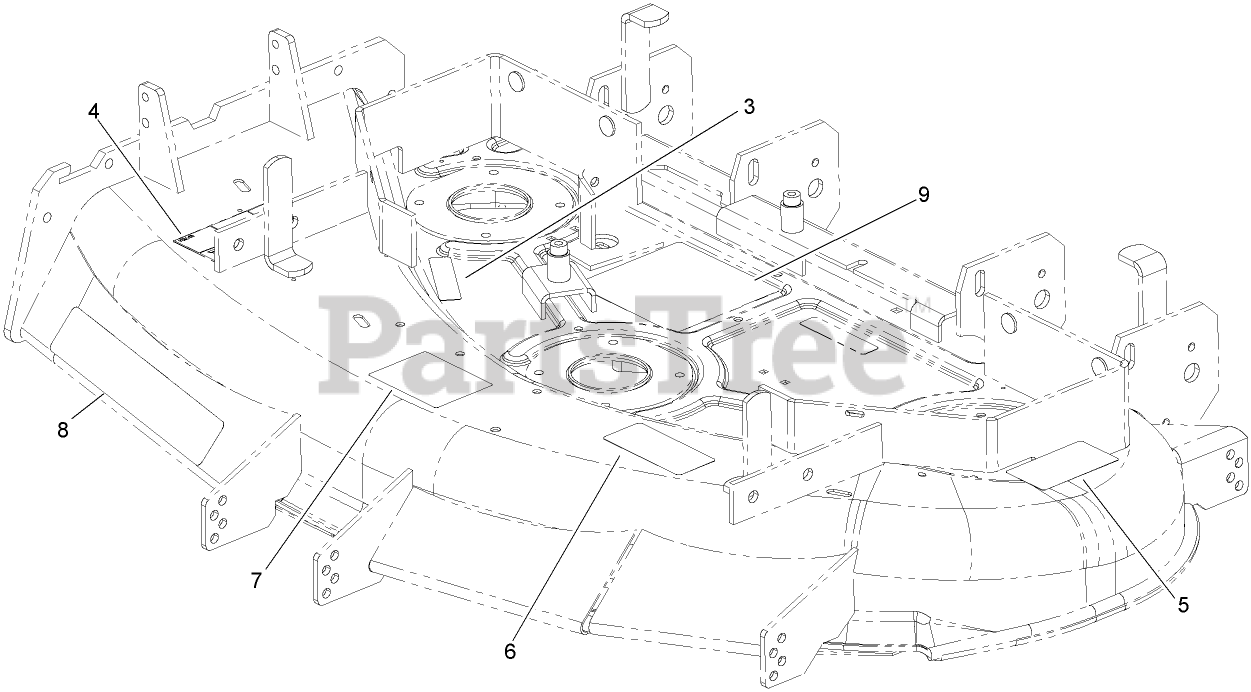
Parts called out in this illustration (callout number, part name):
3	DECAL-WARNING
4	DECAL-DANGER
5	DECAL-DANGER
6	DECAL-TORQUE, BLADE BOLT
7	DECAL-ANTI SCALP
9	DECAL-SERVICE AID, BELT ROUTING
